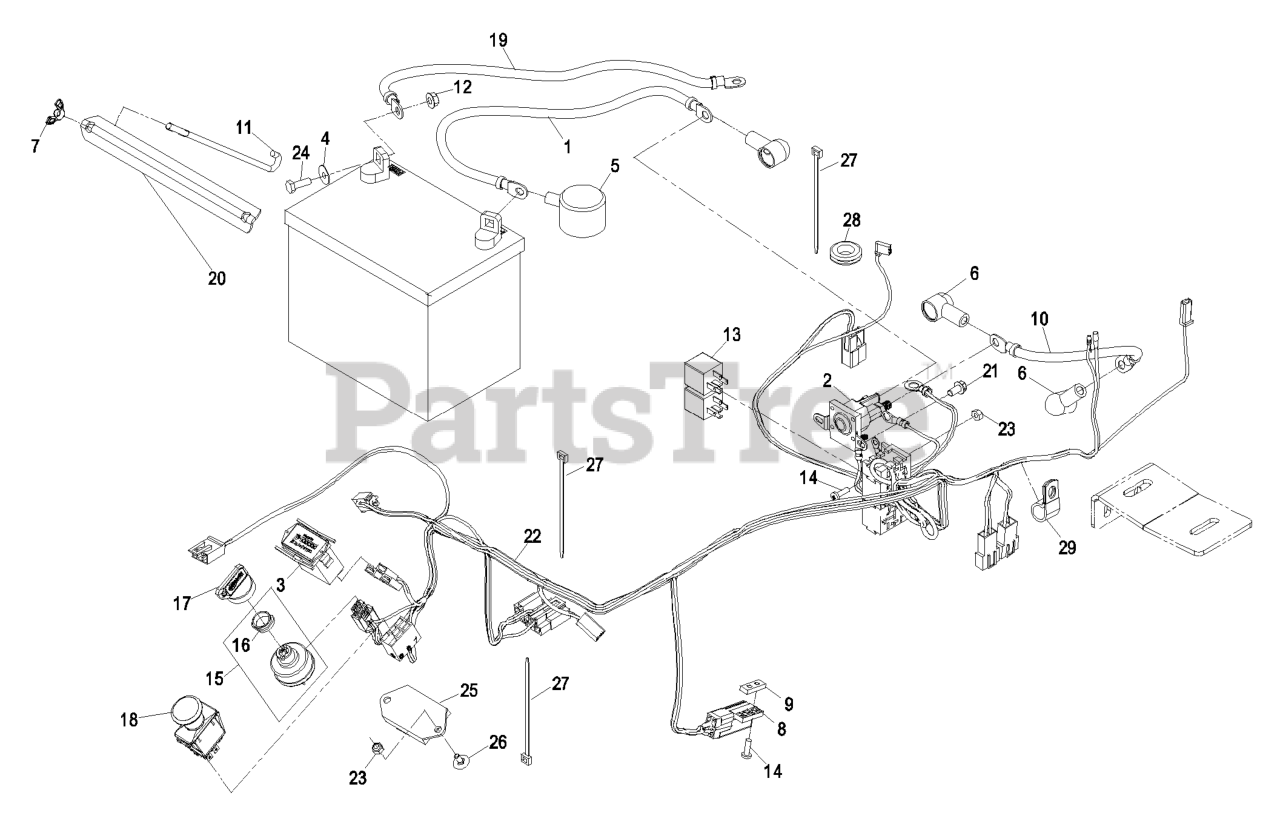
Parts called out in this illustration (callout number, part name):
1	POSITIVE BATTERY CABLE AS
3	METER-HOUR
4	WASHER-FLAT
5	INSULATOR-BATTERY
6	INSULATOR-SOLENOID
7	WINGNUT
9	PLATE-TAPPED
10	POSITIVE STARTER CABLE AS
11	BOLT-HOLDDOWN
14	SCREW-PPH
15	ASM,SWITCH W/NUT
16	NUT-SWITCH, IGNITION
17	KEY-IGNITION
18	SWITCH-PTO
19	CABLE-BATTERY, NEGATIVE
20	ANGLE-BATTERY
21	SCREW-HWH
22	HARNESS-WIRE
23	NUT-LOCK, NI
24	SCREW-HH
25	MODULE-DELAY, SEAT
26	BOLT-CARR
27	TIE-PLASTIC
28	GROMMET
29	CLIP-LOOM
